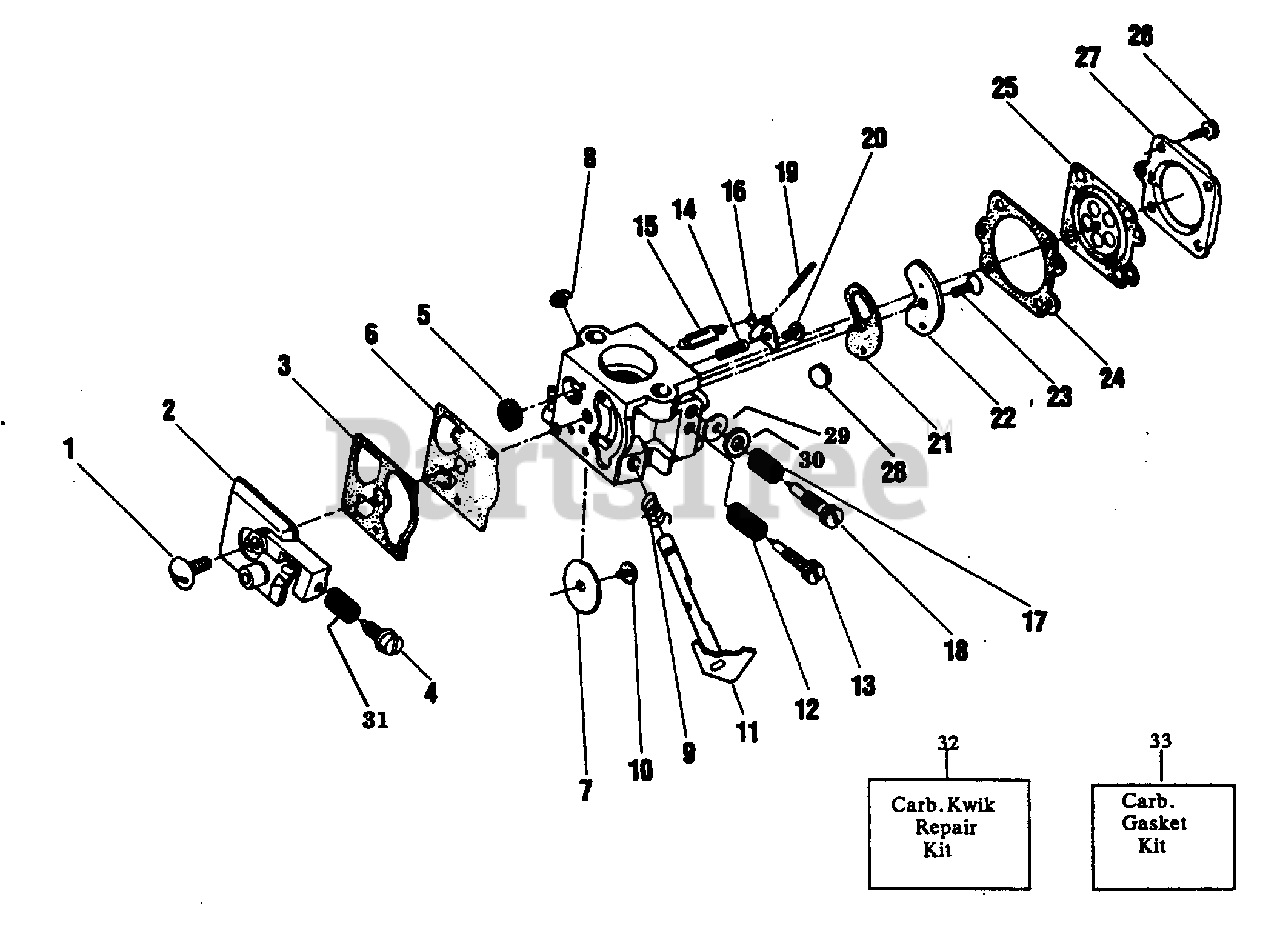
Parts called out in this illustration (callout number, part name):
1	Screw-Pump Cover
2	Pump Cover Ass'y. (Inc.4)
3	Gasket-Pump
4	Screw-Idle Adjustment-
5	Screen-Inlet
6	Diaphragm-Pump
7	Valve-Throttle
8	Clip-Throttle Shaft
9	Spring-Throttle Return
10	Screw-Throttle Valve
11	Shaft Ass'y.-Throttle
14	Spring-Metering Lever
15	Valve-Inlet Needle
16	Lever-Metering
17	Spring-Hi Speed Needle
18	Needle-High Speed
19	Pin-Metering Lever
20	Screw-Metering Lever Pin
21	Gasket-Circuit Plate
22	Plate-Circuit
23	Screw-Circuit Plate
24	Gasket-Metering Diaphragm
25	Diaphragm Ass'y.-Metering
26	Screw Ass'y.-Metering Cover & Throttle Shaft Clip
27	Cover-Metering Diaphragm
29	"O" Ring Mixture
30	Mixture Washer
31	Spring-Idle Speed
32	Kit-Carb. Kwik Repair
33	Kit-Carb. Gasket/Diaphragm
